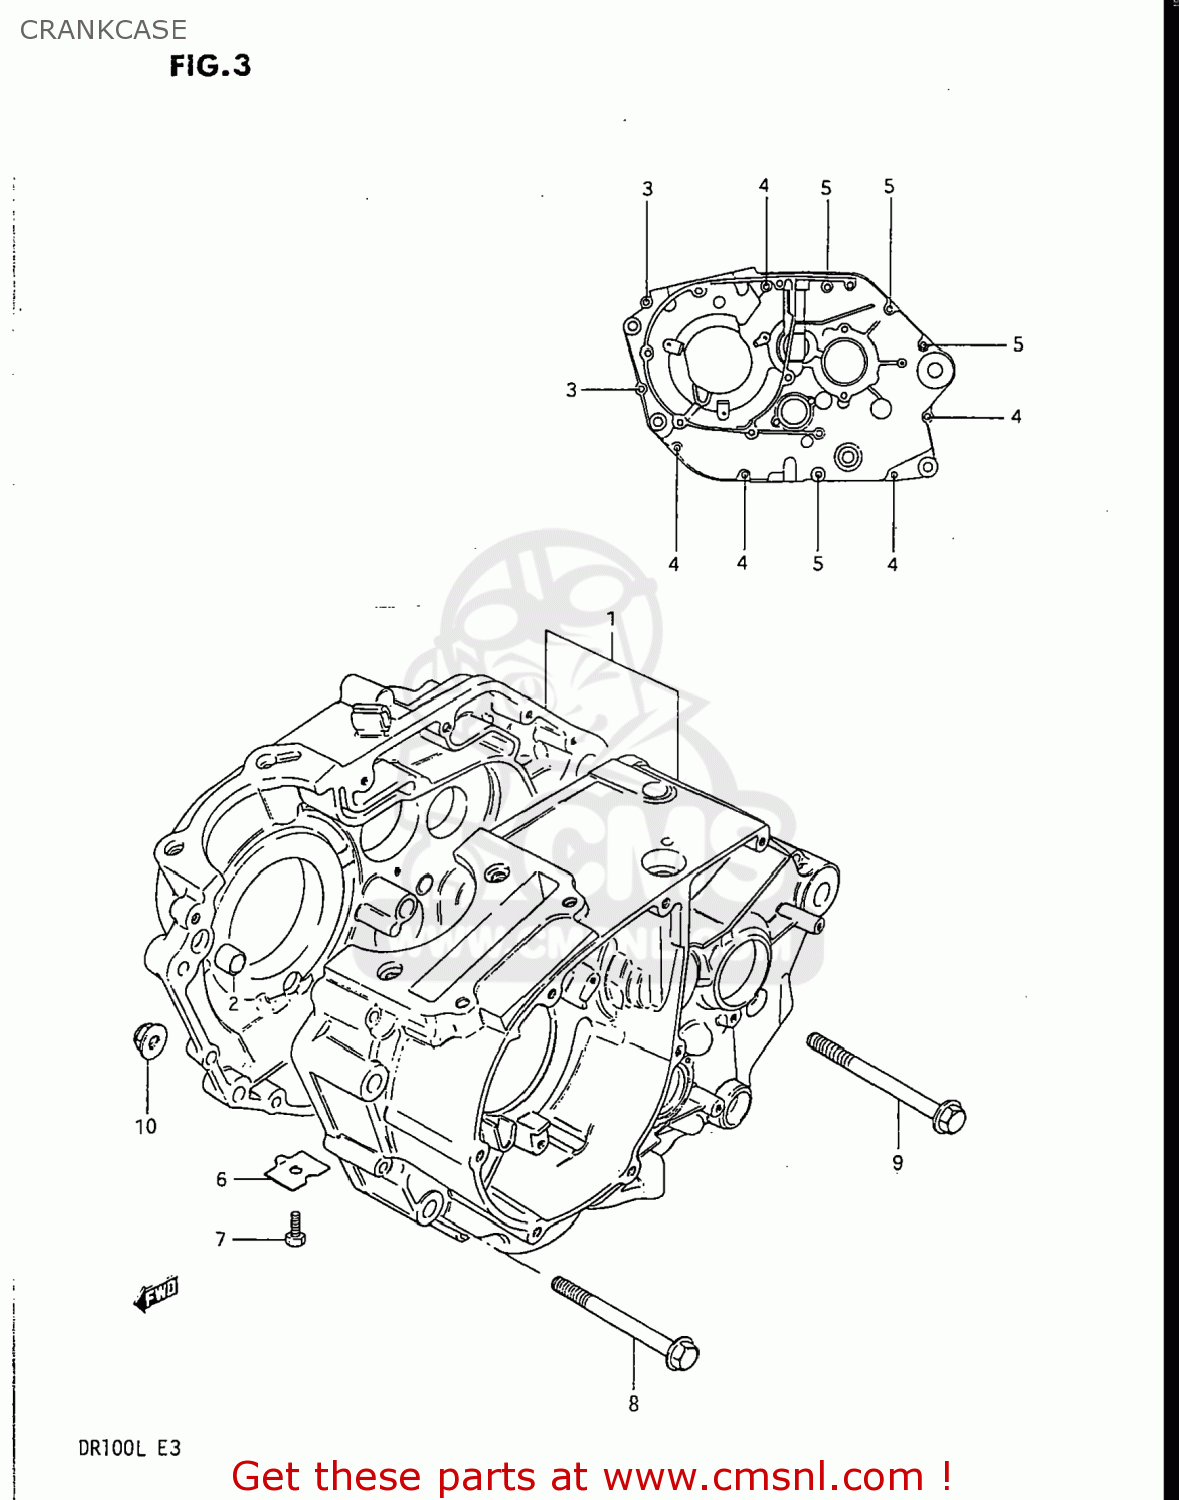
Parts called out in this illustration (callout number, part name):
1	CRANKCASE ASSEMBLY
2	PIN
3	BOLT
4	BOLT (6X60)
5	BOLT (6X75)
6	PLATE,OIL GALLERY PLUG
7	BOLT
8	BOLT(8X80)
9	BOLT 8X88
10	NUT
